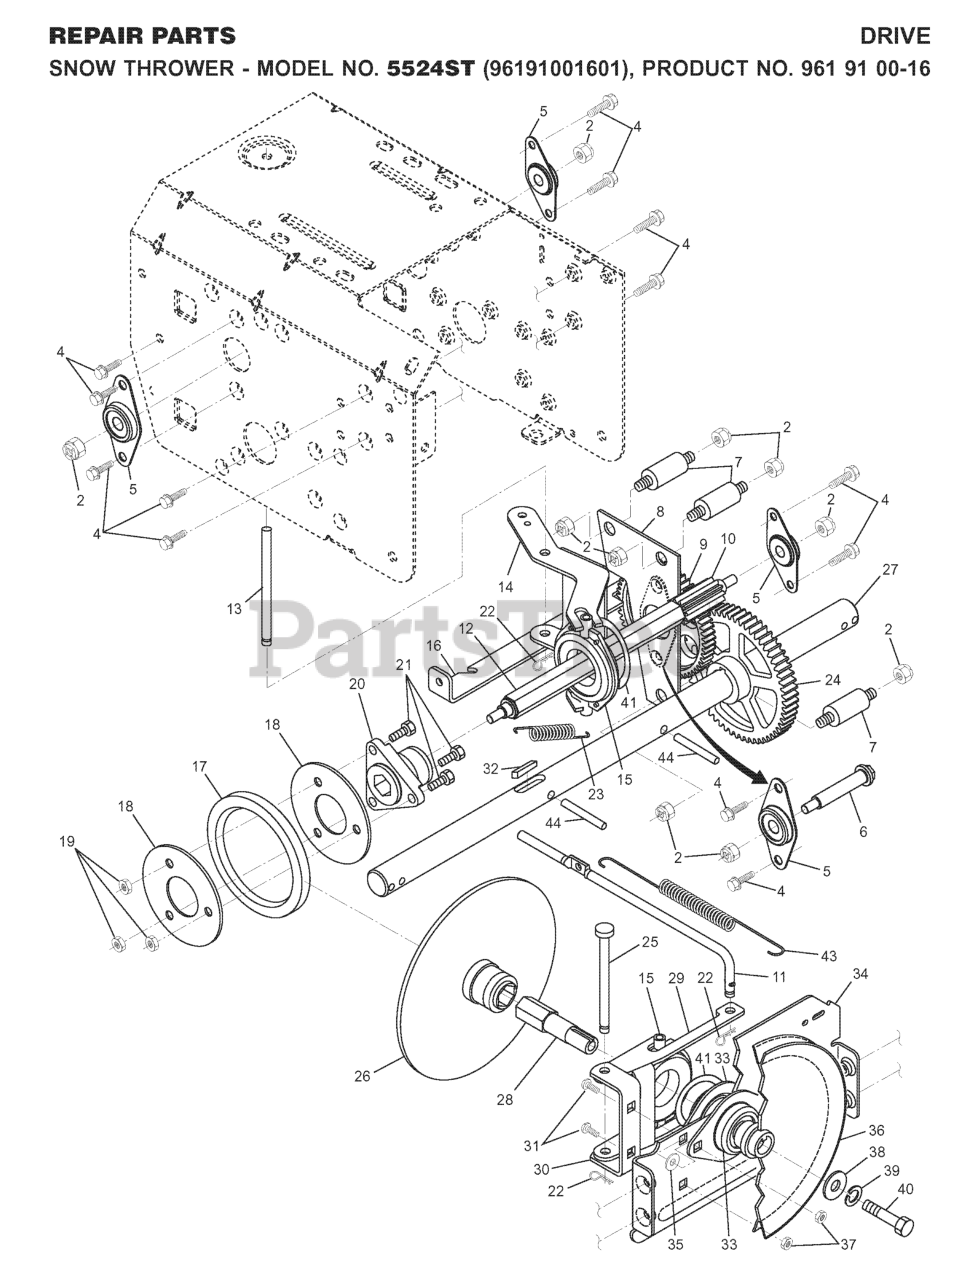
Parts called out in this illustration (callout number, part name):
2	SPRING BRAKE
2	NUT.LOCK.5/16-18
3	PULLEY, TRANSAXLE
4	Screw 5/16-18 x 1/2 Hex, Self Tapping 5/16-18 x 1/2
5	BEARING, FLANGE
6	SHAFT, AUXILIARY
7	SPACER, PLATE
8	ROD SHIFT FENDER ADJUST STLT
8	AUXILLARY PLATE
9	CLUTCH.ELECT.EVX.
9	GEAR, INTERMEDIATE
10	PIN COTTER
10	GEAR, PINION
11	ROD.CLUTCH.YELLOW.ZINC
12	SHAFT.HEX.LONG
13	PIN, PIVOT
14	LOCKWASHER
14	LEVER, SPEED CONTROL
15	TRUNNION BEARING ASSY
16	NUT.71038.31-18.HEX.NYLOCK
16	BRACKET, PIVOT, SHIFT
17	RING, RUBBER WHEEL
18	PLATE.RUBBER.WHEEL
19	NUT
19	NUT.CENTERLOCK.5/16-
20	BOLT HEX
20	HUB, RUBBER WHEEL
21	KNOB.DELUXE.(PISTOL.GRIP).BLAC
21	BOLT
22	ROD BRAKE HYDRO
22	RETAINER CLIP PM
23	BRACKET, ASM CLUTCH MTG
23	SPRING, BIAS
24	NUT
24	GEAR, AXLE (58T)
25	SPRING ROD LT
25	PIN, PIVOT LEVER
26	WASHER
26	DRIVE PLATE WELDMENT
27	COTTER PIN
27	SHAFT.AXLE.16".SNOW
28	ROD BRAKE PARK LT
28	SHAFT.HEX.SHORT
29	PLUNGER CAP
29	LEVER.SHIFTER.PLATE.BLACK
30	BRACKET TRANSAXLE
30	BRACKET, SHIFTER SUPPORT
31	BOLT
32	BOLT
32	KEY, SQUARE 1/4 X .875
33	RP BOLT 5/16-18 X3/4 ZN/YEL GR
33	BEARING FLANGE
34	SHAFT, FOOT PEDAL
34	PLATE.DRIVE.MOUNTING.BLACK
35	BEARING.NYLON
35	SPACER, BEARING
36	PULLEY.TRACTION.7.75
37	DRIVE PIN
37	NUT.FLANGE.5/16
38	FLAT IDLER PULLEY
38	WASHER, FLAT
39	WASHER.LOCK.HVY.HLCL.SPR.5/16
40	Screw, Hex Head 5/16-18 x 3/4
41	KEEPER.BELT.IDLER.FLAT
41	RETAINING RING (2 2)(3 2)
42	WASHER
43	SPRING.RETURN
44	PIN.ROLL.3/16
47	IDLER PULLEY
48	BELLCRANK, CLUTCH
49	RETAIN BELT
50	BOLT
52	LOCKNUT
53	LINK, CLUTCH LT
55	SPRING, RETURN LT
57	DRIVE BELT, LTH & YTH TRACTORS
59	KEEPER CENTER SPAN
61	SCREW
62	COVER, PEDAL (1 2)
63	PULLEY, CLUTCH ELECT EVX
65	LOCKWASHER
66	KEEPER BELT ENGINE
71	STRAP LH TORQUE
73	STRAP TORQUE RH HYDRO
74	SPACER SPLIT
77	SQUARE KEY
81	Shaft Asm Cross Tapered 650 20
83	WASHER
84	LINK, TRANSAXLE
89	SHIFT CONSOLE
90	NUT.PUSH.3/16
93	LINE FUEL HYD 4"
94	FAN 7" HYDRO
95	CONTROL ARM, BYPASS HYDRO
96	RETAINER M
97	KEEPER BELT RH
100	WASHER M
103	NUT.HEX.1/2-20
104	CONTROL ARM
106	BOLT.5/16-18X1-1/4 FULL.THREAD
144	Washer 11/32 x 5/8 x 16 Ga SD
146	Bolt Hex Flanged 5/16-18 Unc x 2
147	Bolt Hex Flanged 5/16-18 Unc x 2
150	BUSHING.BELLCRANK.GRD.DR
151	WASHER 12/32X2X10GA
156	WASHER.SRRTD.5/16
157	BOLT SHOULDER 5/16-18
158	BRACKET
159	HUB
160	Washer 29/32 x 1 - 1/4 x 16 Ga.
161	BOLT
162	NUT.CROWNLOCK.1/4
164	Washer 5/8 x .281 x 10 Ga.
165	RP BRACKET
168	BOLT.SHOULDER.5/16-18X
169	PLATE.FASTENING.CROSS.SHAFT
